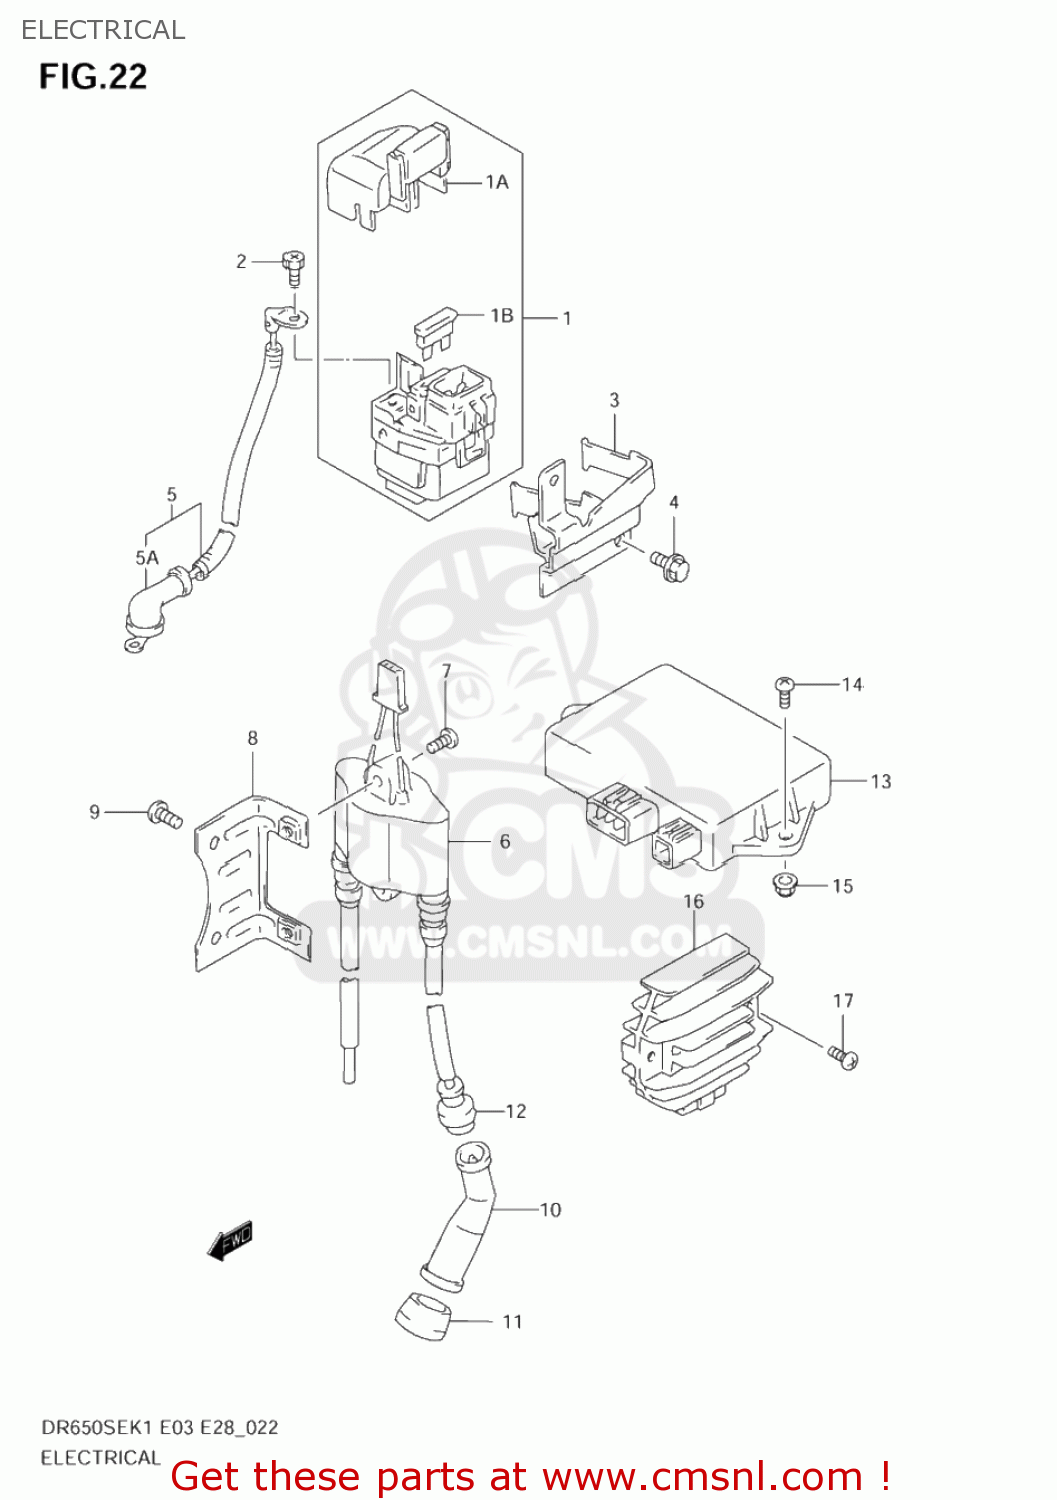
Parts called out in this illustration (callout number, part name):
1	RELAY ASSY,STARTING MOTOR
1A	COVER,STARTER RELAY
1B	FUSE(30A)
2	SCREW(6X8)
3	BRACKET,STARTING MOTOR RELAY
4	BOLT(6X8)
5	WIRE,STARTER MOTOR
5A	CAP,STARTER MOTOR LEAD
6	COIL ASSY,IGNITION
7	SCREW
8	BRACKET,IGNITION COIL
9	SCREW 6X10
10	CAP,SPARK PLUG
11	SEAL,SPARK PLUG
12	SEAL,HIGH TENSION CORD
13	CDI UNIT
14	BOLT
15	NUT
16	RECTIFIER ASSY
17	BOLT
